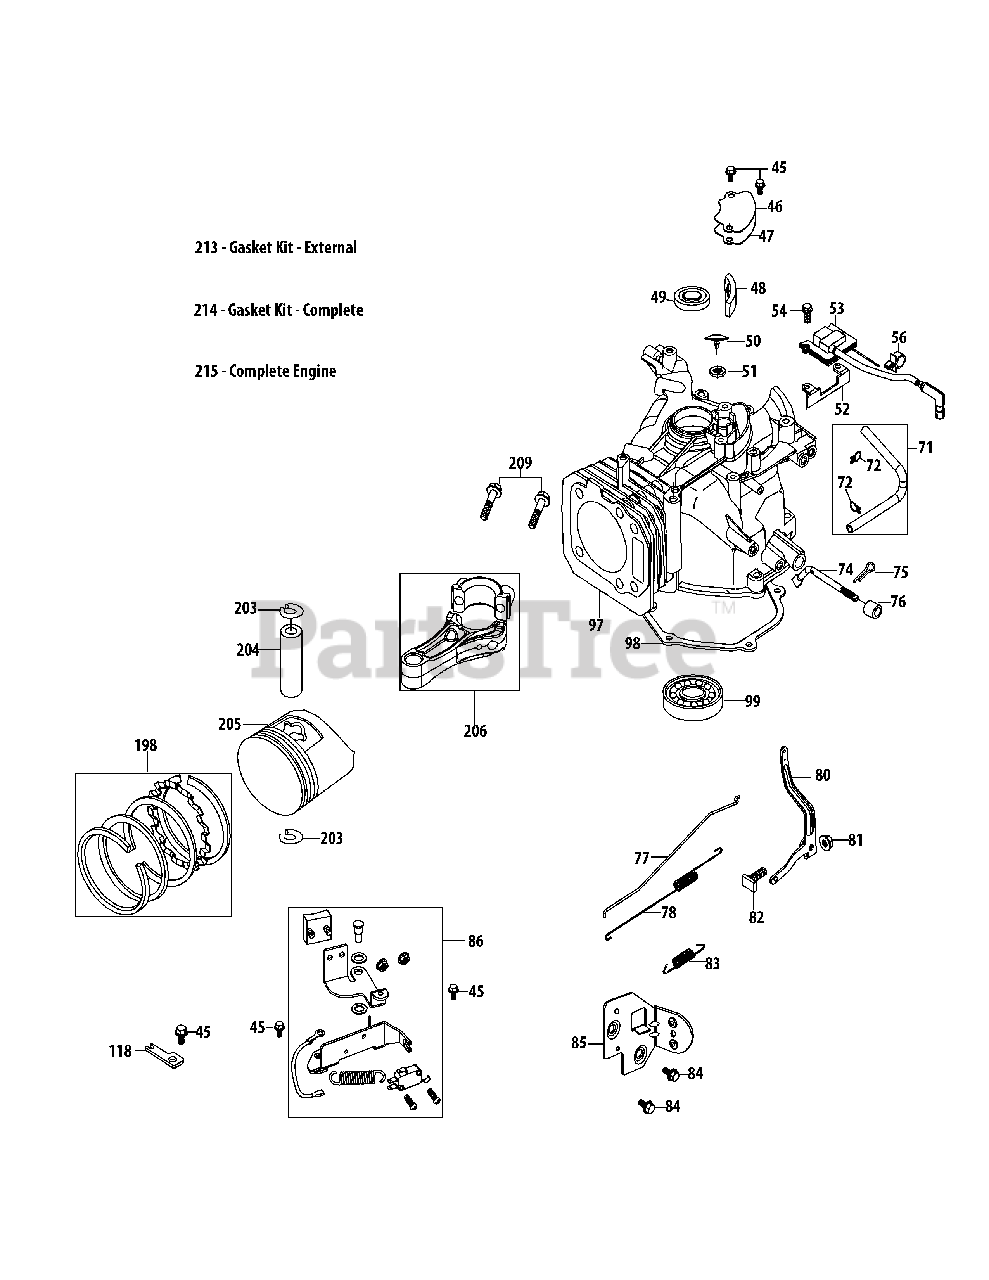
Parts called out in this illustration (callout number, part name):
45	Bolt M6×14
46	Breather Cover Plate
47	Breather Gasket
48	Breather Screen
49	Upper Crankshaft Seal
50	Breather Valve
51	Breather Valve Base
52	Ignition Coil Bracket
53	Ignition Coil Assembly
54	Bolt M6X18
56	Ignition Wire Clip
71	Breather Hose Assembly
72	Breather Hose Clamp
74	Governor Arm Shaft
75	Governor Arm Shaft Cotter Pin
76	Governor Seal
77	Throttle Linkage
78	Throttle Linkage Spring
80	Governor Arm
81	Governor Arm Nut M6
82	Governor Arm Bolt
83	Governor Spring
84	Bolt M6X12
85	Primer Bracket
86	Brake Assembly
97	Short Block Assembly
98	Crankcase Cover Gasket
99	Main Bearing
118	Governor Gear Mounting Plate
198	Piston Ring Set
203	Piston Pin Snap Ring
204	Piston Pin
206	Connecting Rod Assembly
209	Connecting Rod Bolt
213	Gasket Kit - External
214	Gasket Kit - Complete
215	Complete Engine
